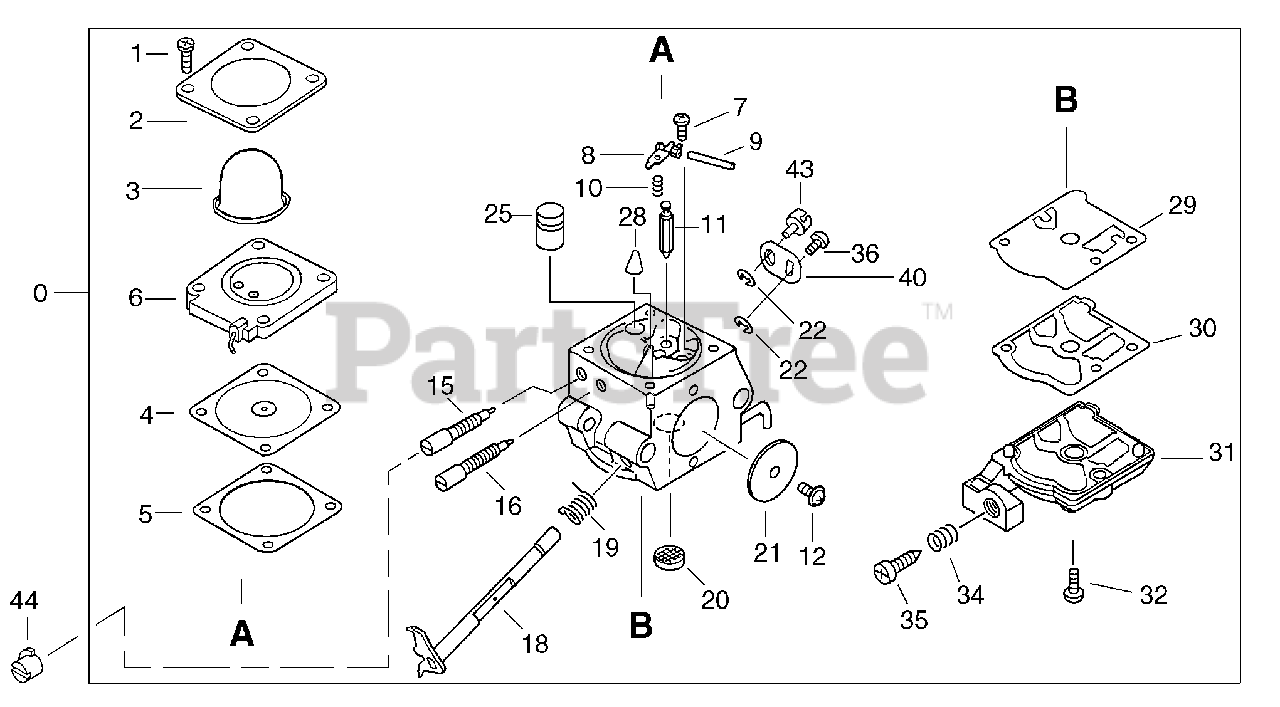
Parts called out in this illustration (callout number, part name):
1	SCREW, RETAINER
2	RETAINER, PURGE BULB
3	BULB, PURGE
4	DIAPHRAGM, METERING
5	GASKET, METERING
6	PURGE BASE ASSY
7	SCREW, METERING LEVER PIN
8	LEVER, METERING
9	PIN, METERING LEVER
11	VALVE, INLET NEEDLE
15	NEEDLE - HIGH SPEED
16	NEEDLE - LOW SPEED
18	THROTTLE VALVE ASSY
19	SPRING, THROTTLE RETURN
20	STRAINER
21	VALVE, THROTTLE
22	RING, RETAINING
25	NOZZLE, CHECK VALVE
28	PLUG, WELCH
29	DIAPHRAGM, PUMP
30	GASKET, PUMP
31	COVER, PUMP
32	SCREW, PUMP COVER
34	SPRING, IDLE ADJUST
35	SCREW, IDLE ADJUST
40	LEVER, THROTTLE
44	CAP, LIMITER
